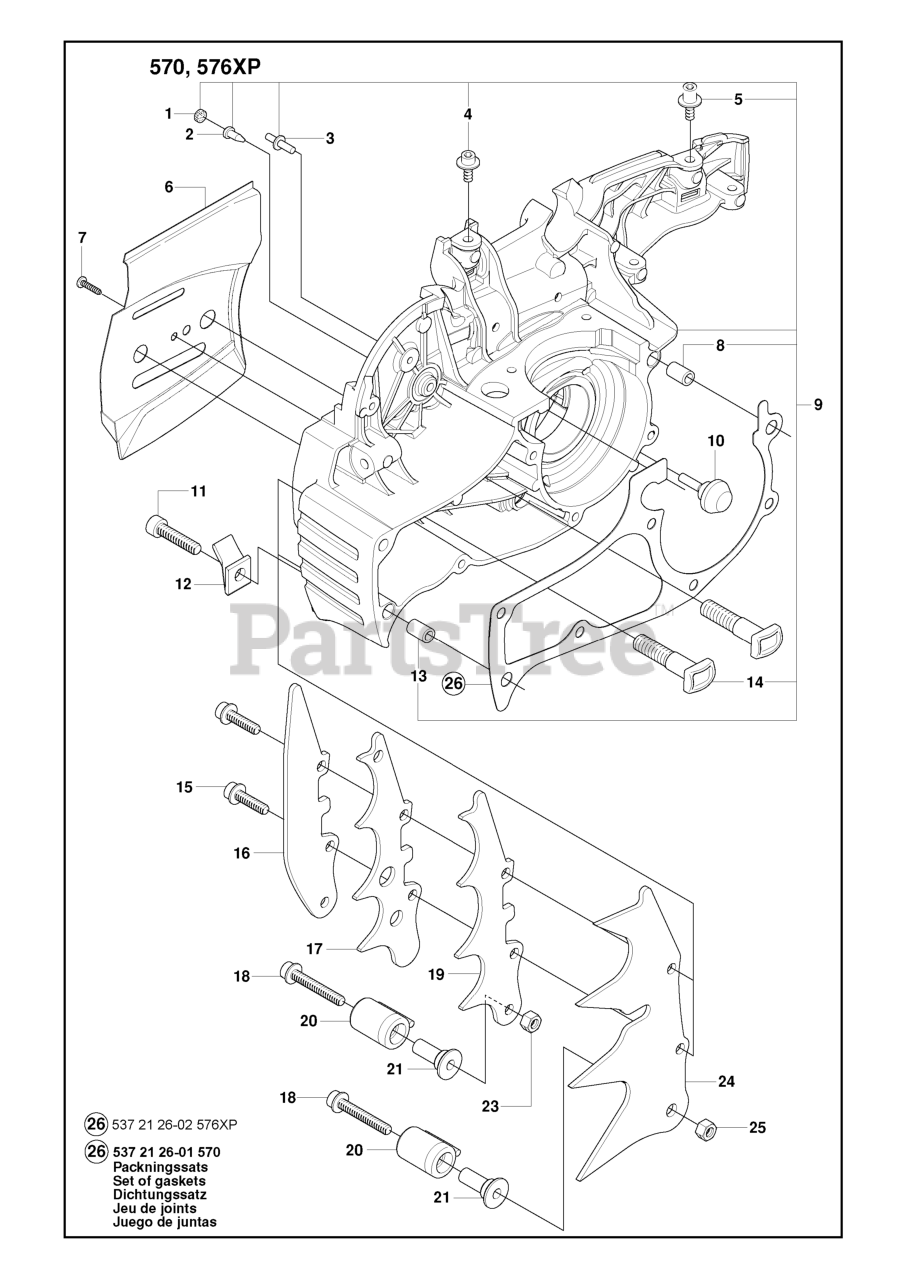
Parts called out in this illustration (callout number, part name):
1	PLUG
2	VALVE-CHECK (DUCKBILL)
4	SCREW IHSCM
5	SCREW IHSCM
8	SLEEVE
9	RP CRANKCASE ASSEMBLY
9	CRANKCASE ASSY
12	CHAIN CATCHER
13	SLEEVE
17	FELLING DOG
18	SCREW
19	FELLING DOG
21	CHAIN CATCHER
22	SCREW
24	FELLING DOG
26	GASKET SET
26	GASKET KIT
